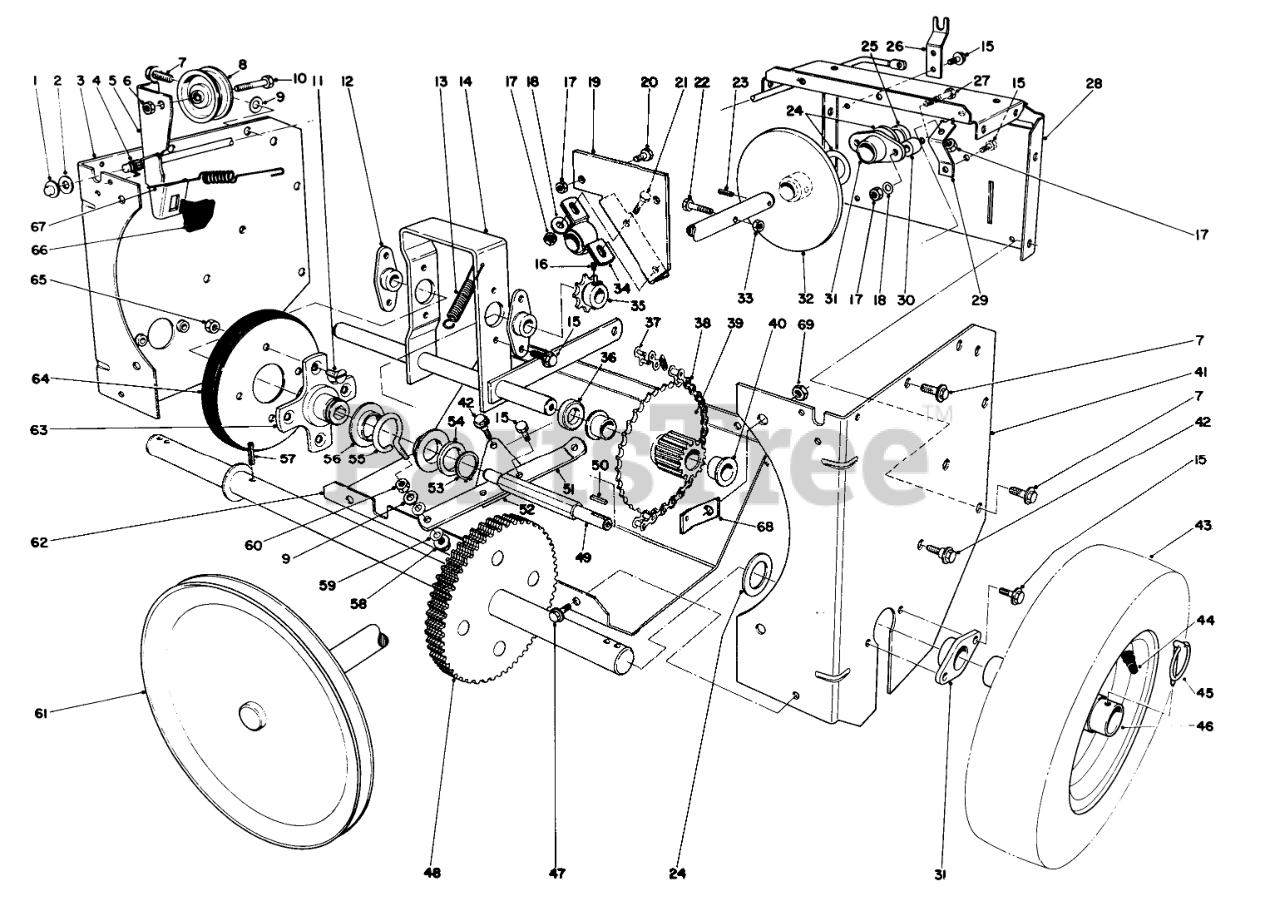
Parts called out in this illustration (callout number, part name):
1	PUSH NUT
2	WASHER-FLAT
3	RH TRACT SIDE PLT R
4	TORSION CLUTCH SPRING
5	Rod-Clutch (Incl. Ref. #66)
6	NUT-LOCK, NI
7	SCREW-HHFTF
8	PULLEY-IDLER
9	WASHER-FLAT
10	SCREW-HH
11	5/16-18X5/8 FLT HD MS
12	BEARING-WHEEL, FRICTION
13	TENSION SPRING
14	PIVOT SHAFT WA B
15	SCREW-HWHTF
16	SCREW-HSH
17	NUT-LOCK, NI
18	WASHER-PLAIN
19	SHAFT SUPT BRKT B
20	SCREW-HH
21	SCREW-HH
22	SCREW-HH
23	PIN-ROLL, SLOTTED
24	WASHER
25	DRIVE SHAFT SPACER
26	CLUTCH ROD SUPPORT
27	SCREW-HH
28	CENTER FRAME R
29	PIVOT BRACKET
30	BRG STANDOFF
31	AXLE BEARING
32	FRICTION PLT WA
33	NUT-HEX
34	PILLOW BLOCK BRG
35	SPROCKET
36	COSHAFT SPACER
37	LINK-CONNECTING
38	ROLLER-CHAIN
39	Gear & Bushing Assembly (Incl. Ref. #40)
40	BUSHING
41	LH TRACT SIDE PLT R
42	SHOULDER SCREW
44	TUBE-INNER
45	PIN-LYNCH
46	WHEEL
47	SCREW-HWH
48	AXLE & GEAR WA
49	FRICTION WHL SHAFT
51	SHIFT LINKAGE
52	PIVOT PLATE
53	RING-RETAINING
54	WASHER-THRUST
55	SLIDER RING COLLAR
56	SLIDER RING
57	PIN-ROLL, SLOTTED
58	NUT-LOCK, FLANGE
59	WASHER-SPRING
60	NUT-LOCK
61	PULLEY/SHFT WA
62	LOWER SHIELD R
63	TRACTION DISC HUB
64	FRICTION WHEEL
65	NUT-LOCK, NI
66	PAD-BRAKE
67	SPRING
68	FRONT SPRING ARM ASM
69	NUT-LOCK, SIDE
70	SPRING
